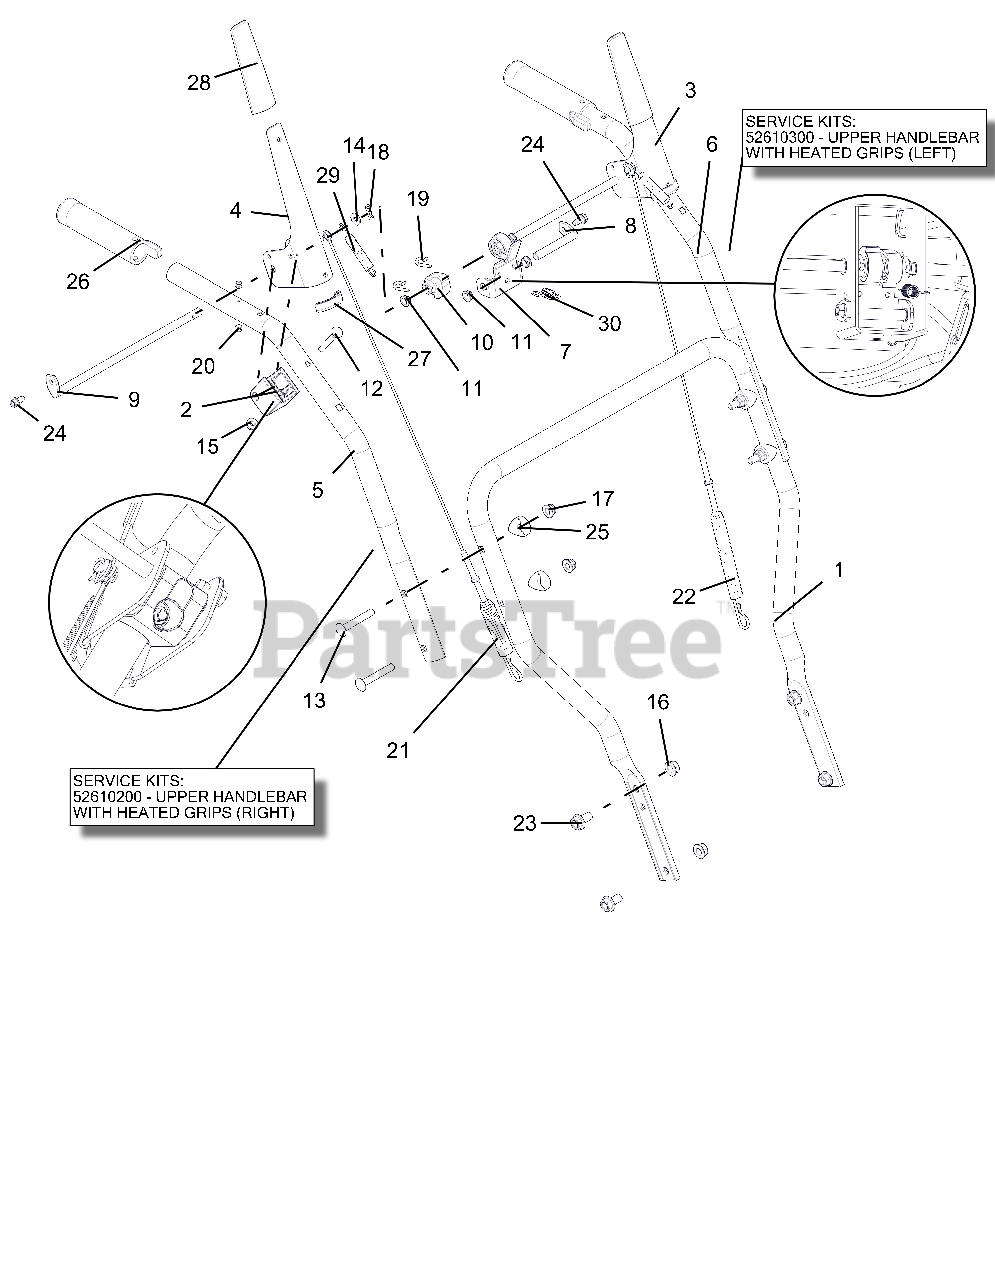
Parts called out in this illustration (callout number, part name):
1	HANDLEBAR, LOWER
2	BLOCK, CLUTCH PADDLE
3	LEVER, CLUTCH-LH
4	LEVER, CLUTCH-RH
5	HANDLEBAR, UPPER - RH
5	HANDLEBAR, UPPER RH W/HW
6	HANDLEBAR, UPPER - LH
6	HANDLEBAR, UPPER LH W/HW
7	BRACKET, INTERLOCK ARM
8	ROD, PIVOT - INTERLOCK
9	ROD, PADDLE MOUNT - PRO
10	CAM, INTERLOCK
11	BUSHING, POLYLINER-.38 SNAPIN
12	BLT-RDHDXLSQNK .25-20X2.0 G5YZ
13	@BLT-RDHDSQNK .31-18X2.25 G5YZ
14	@WSHR-FL-STL.281X.62X.065 YWZC
15	@NUT-LK-CTR-FLG .25-20 YWZC
16	@NUT-LK-TOP-FLG .38-16 YWZC
17	@NUT-LK-NYL-FLG .31-18 YWZC
18	PIN-HAIR INT .06X.18X.77
19	PIN, SPRING CLIP
20	RVT-POP #43 .125X.313 STL ZINC
21	CABLE, AUGER (DELUXE & PRO)
22	CABLE, UPPER TRACTION
23	BLT-SERHFWH .38-16X.75 YWZC
24	SCR-TAP .25-20X.50 HWH TR YWZ
25	SPACER, HANDLEBAR
26	HEATED GRIP, MAGURA
27	EDGING, CLUTCH PADDLE - 2.00"
28	CLUTCH PADDLE SLEEVE - GRAY
29	SPRING, EXTENSION
30	SPRING-EXT .047X.438X1.45
